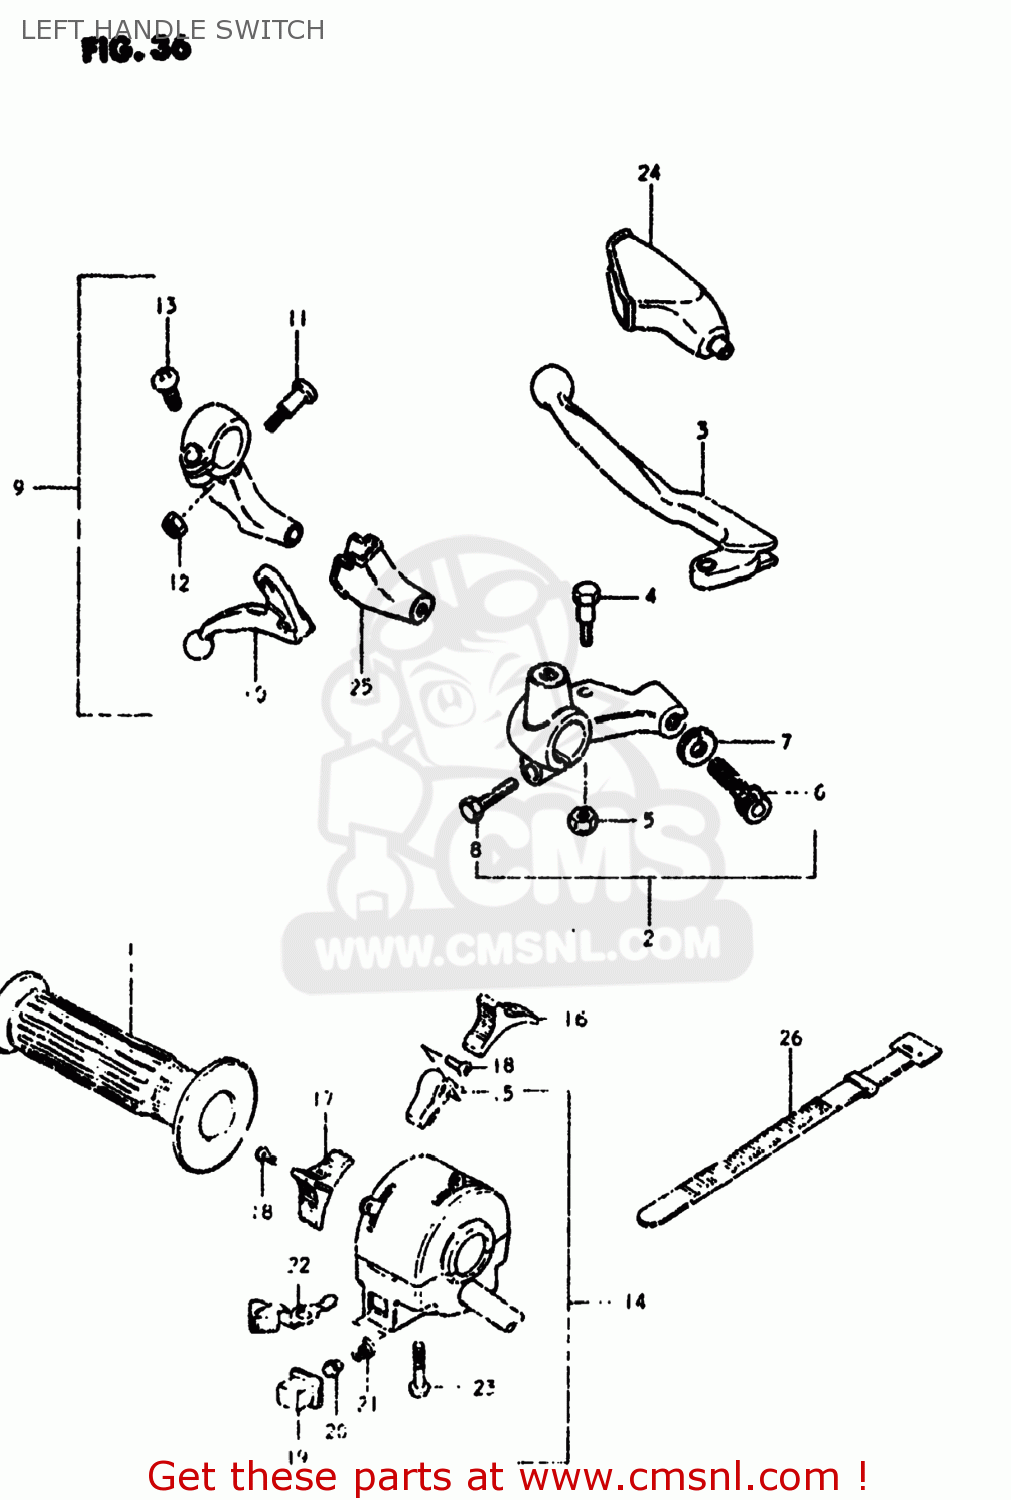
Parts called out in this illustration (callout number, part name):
1	GRIP,L
2	LEVER ASSY,CLUTCH
3	LEVER,CLUTCH
4	BOLT,LEVER
5	NUT 6MM
6	ADJUSTER,CABLE
7	NUT,CABLE ADJUSTER
8	BOLT
9	LEVER ASSEMBLY,DECOMPRESSION
10	LEVER,DECOMPRESSION
11	BOLT,LEVER
12	NUT,LEVER BOLT
13	SCREW
14	SWITCH ASSEMBLY,HANDLE,LEFT
15	KNOB,STOP
16	KNOB,LIGHTING SWITCH
17	KNOB,DIMMER SWITCH
18	SCREW
19	BUTTON,HORN
20	CONTACT
21	SPRING
22	KNOB,TURNSIGNAL
23	SCREW
24	COVER,CLUTCH LEVER
25	COVER,DECOMP LEVER DUST
26	CLAMP(L:120)
